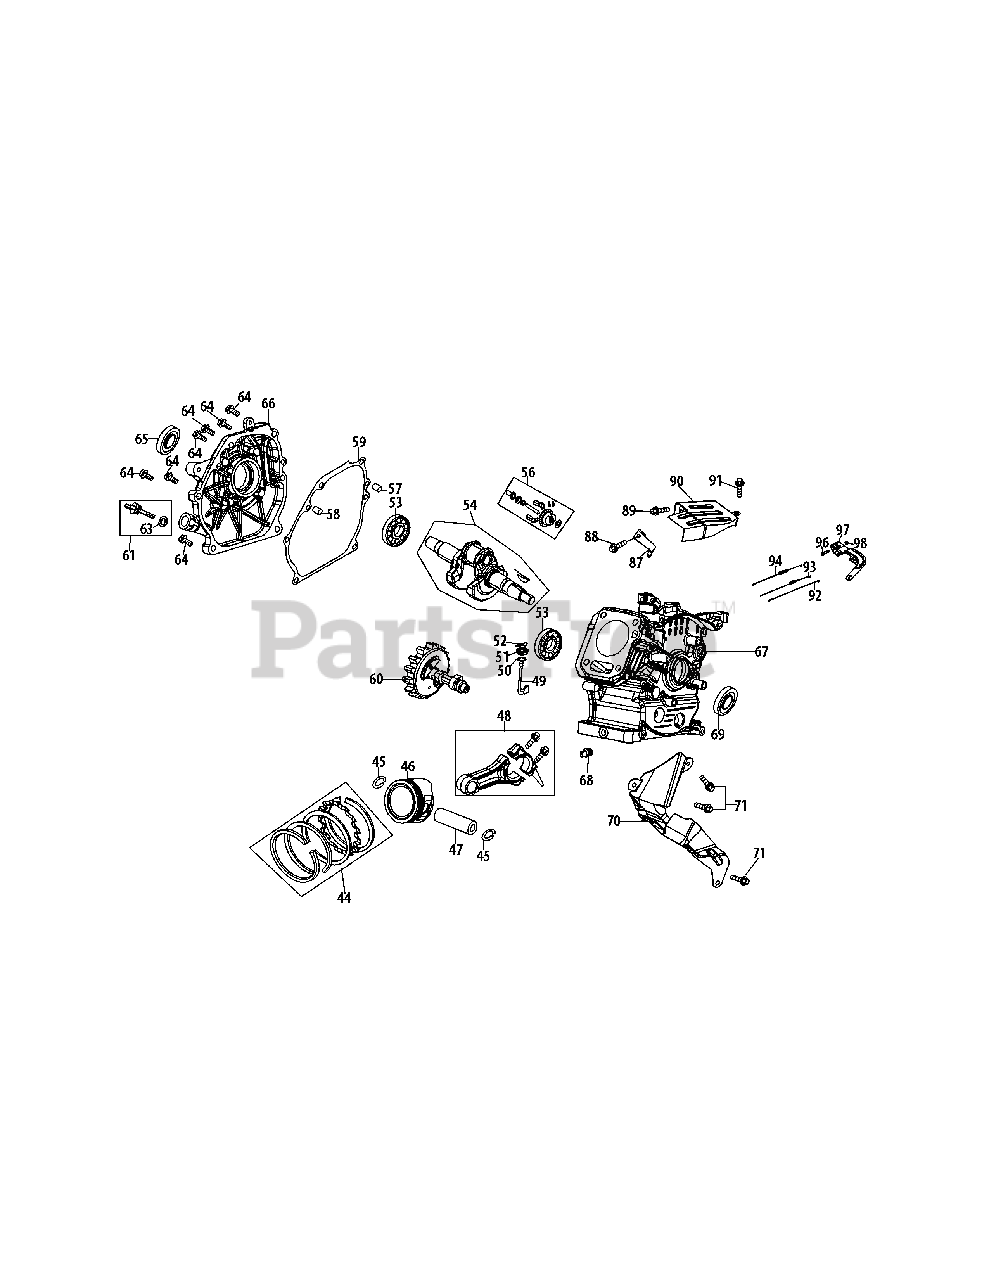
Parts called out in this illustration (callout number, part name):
44	Piston Ring Set
45	Clip, Piston Pin, 18Mm
47	Pin, Piston
48	Connecting Rod Assembly
49	Goverror Arm
51	Governor Seal
52	Pin, Lock
53	Bearing, 6205
54	Crankshaft Kit
55	Woodruff Key
56	Governor Gear/Shaft Assy
57	Pin, Dowel, 9×14
58	Pin, Dowel, 7×14
59	Gasket, Crankcase Cover
60	Camshaft Assy
61	Dipstick Assembly
64	Bolt, Flange, M6×28
65	Oil Seal, 25×41.25×6
66	Crankcase Cover Kit
67	Crankcase Kit
68	1/8 Npt Oil Drain Plug
70	Baffle, Cylinder
71	Bolt, Flange, 6×10
87	Covernor Spring Bracket
88	Boltm6×14
89	Bolt, Flange, 8×14
90	Governor Shield
91	Bolt, Flange, M6×28
92	Rod, Governor
93	Throttle Return Spring
94	Spring, Governor
96	Bolt, Governor Arm
97	Arm, Governor
98	Nut, Flange, 6mm
